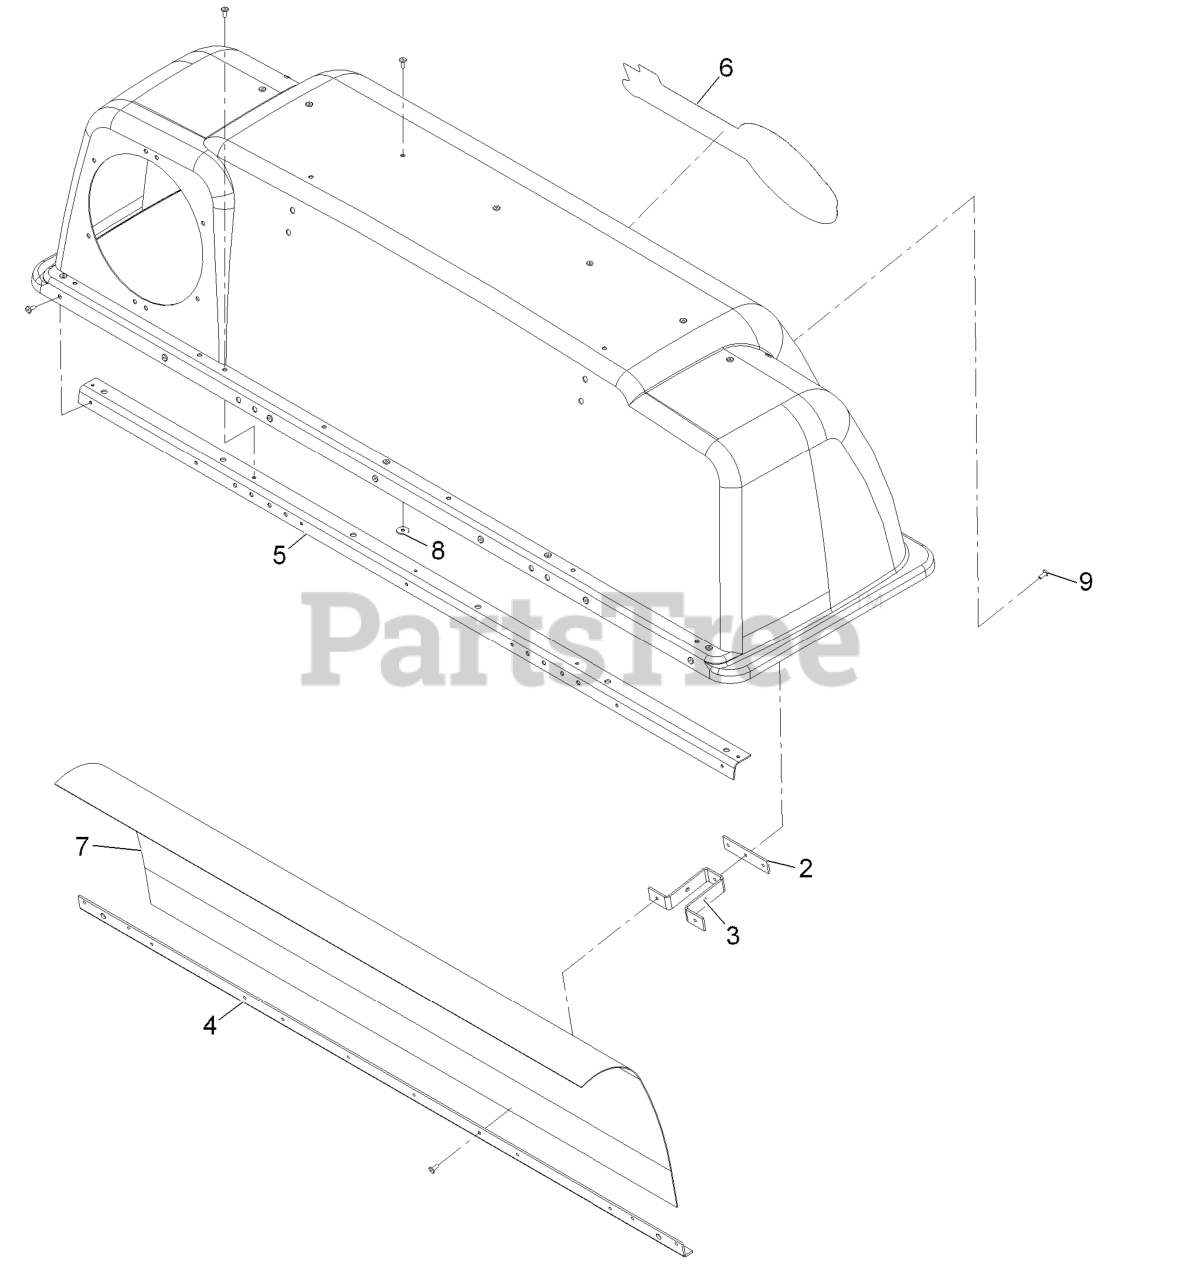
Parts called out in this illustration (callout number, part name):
2	Plate-Latch, Reinforcement
3	Bracket-Mount
4	Support-Screen
5	Stiffener-Bagger, Top
6	Decal-Exmark Logo
7	Screen-Bagger
